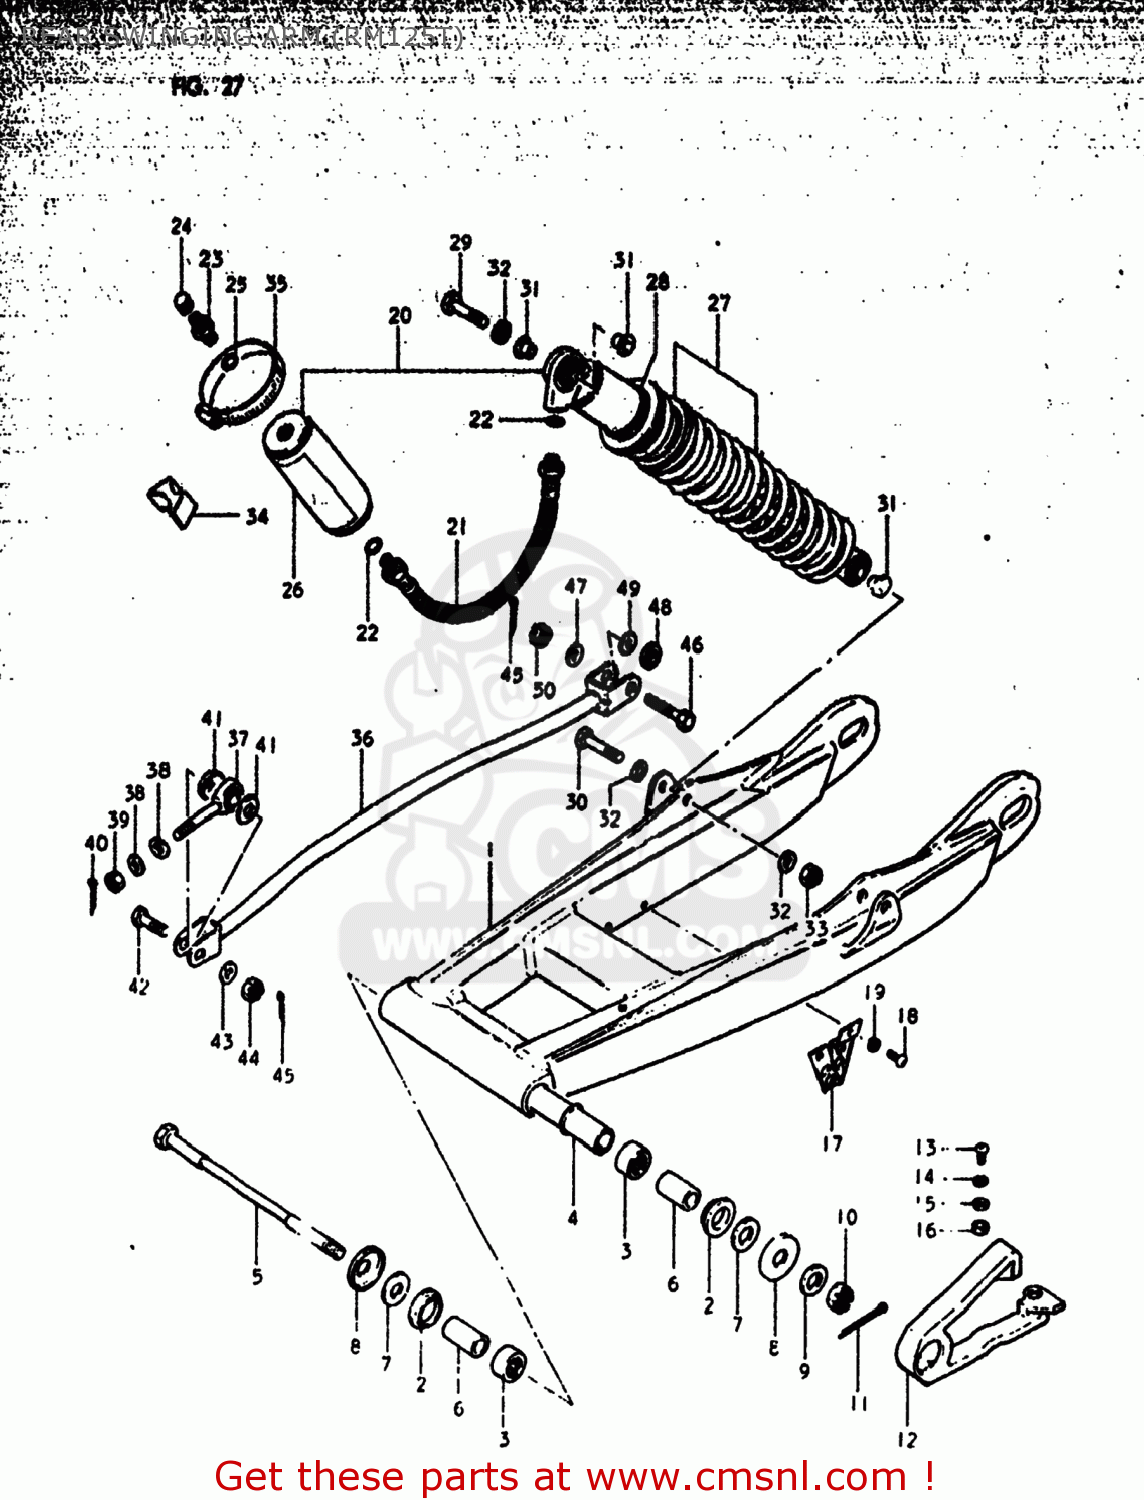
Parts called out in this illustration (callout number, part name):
1	SWING ARM ASSEMBLY,REAR
2	BUSH,RR SWINGINGARM PIVOT
3	ROLLER BEARING (17X24X2
4	SPACER
5	SHAFT,RR SWINGINGARM PIVOT
6	SPACER,RR SWGARM PIVOT
7	WASHER
8	COVER,REAR SWING ARM DUST
9	WASHER
10	NUT, REAR AXLE
11	COTTER PIN
12	BUFFER,CHAIN TOUCH DEFLECTOR
13	SCREW
14	LOCK WASHER
15	WASHER
16	SPACER (5.5X8X4)
17	GUIDE,CABLE
18	SCREW
19	LOCK WASHER
20	ABSORBER ASSEMBLY,REAR SHOCK
21	HOSE,REAR SHOCK ABSORBER
22	O-RING,RESERVE TANK
23	VALVE
24	CAP,VALVE AIR
25	O RING
26	RESERVE TANK,REAR SHOCK
28	STOP, SPRING
29	BOLT
30	BOLT(8X46)
31	SPACER,RR SHK ABS INNER
32	WASHER
33	NUT
34	CUSHION,RR SHOCK ABSORBER
35	CLAMP
36	TORQUE LINK,REAR
37	BEARING
38	WASHER
39	NUT
40	PIN
41	DUST SEAL,TORQUE LINK FR BRG
42	BOLT 8X28
43	WASHER
44	NUT 8MM
45	PIN 20X20
46	BOLT 8X35
47	WASHER
48	49
49	WASHER (8.5X16X2.6)
50	NUT 8MM
